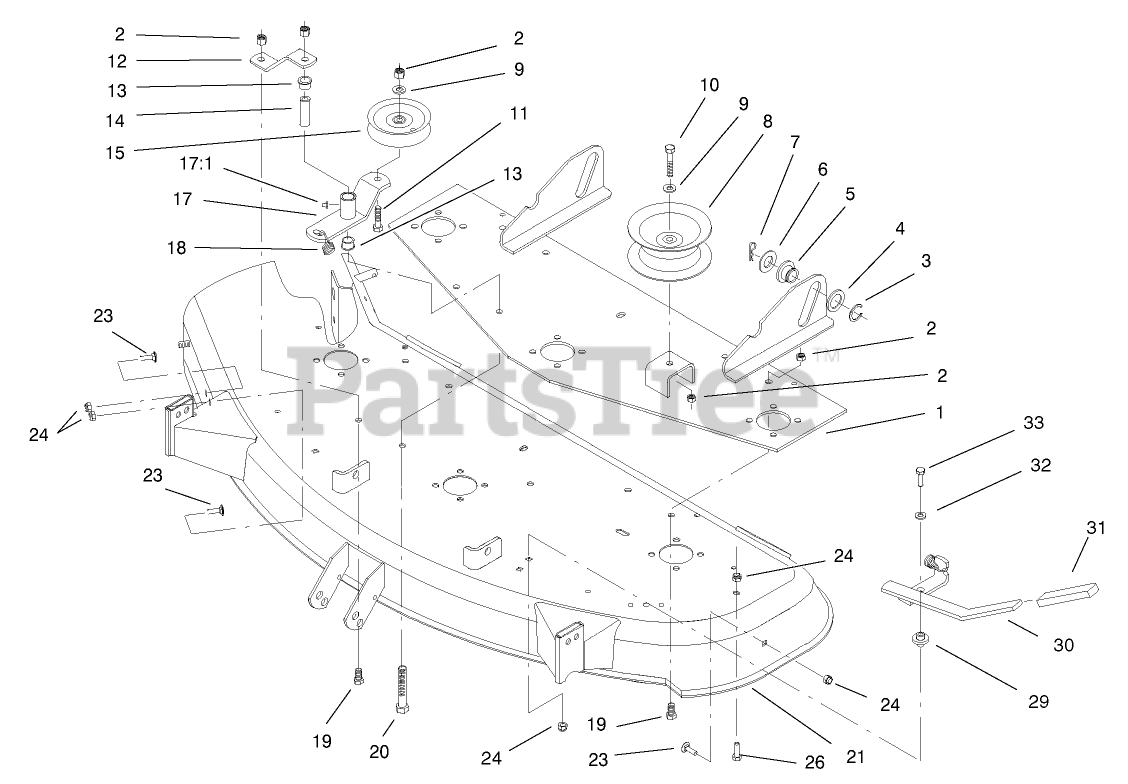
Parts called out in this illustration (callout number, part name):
1	SUPPORT-DECK
2	NUT-LOCK, NI
3	RING-RETAINING
4	WASHER-FLAT
5	ROLLER-LIFT
6	WASHER-FLAT
7	PIN-HAIR
8	PULLEY-IDLER
9	WASHER-FLAT
10	SCREW-HH
11	SCREW-HH
12	STRAP-BRACE
13	BUSHING
14	SPACER
15	PULLEY-IDLER, FLAT
17	ARM-IDLER
17:1	FITTING-GREASE
18	SPRING-EXTENSION
19	SCREW-HH
20	SCREW-HH
23	SCREW-CARR
24	NUT-LOCK, NI
26	SCREW-CARR
29	SPACER-RACK, STEERING
30	LEVER ASM
32	WASHER-PLAIN
33	SCREW-HH
